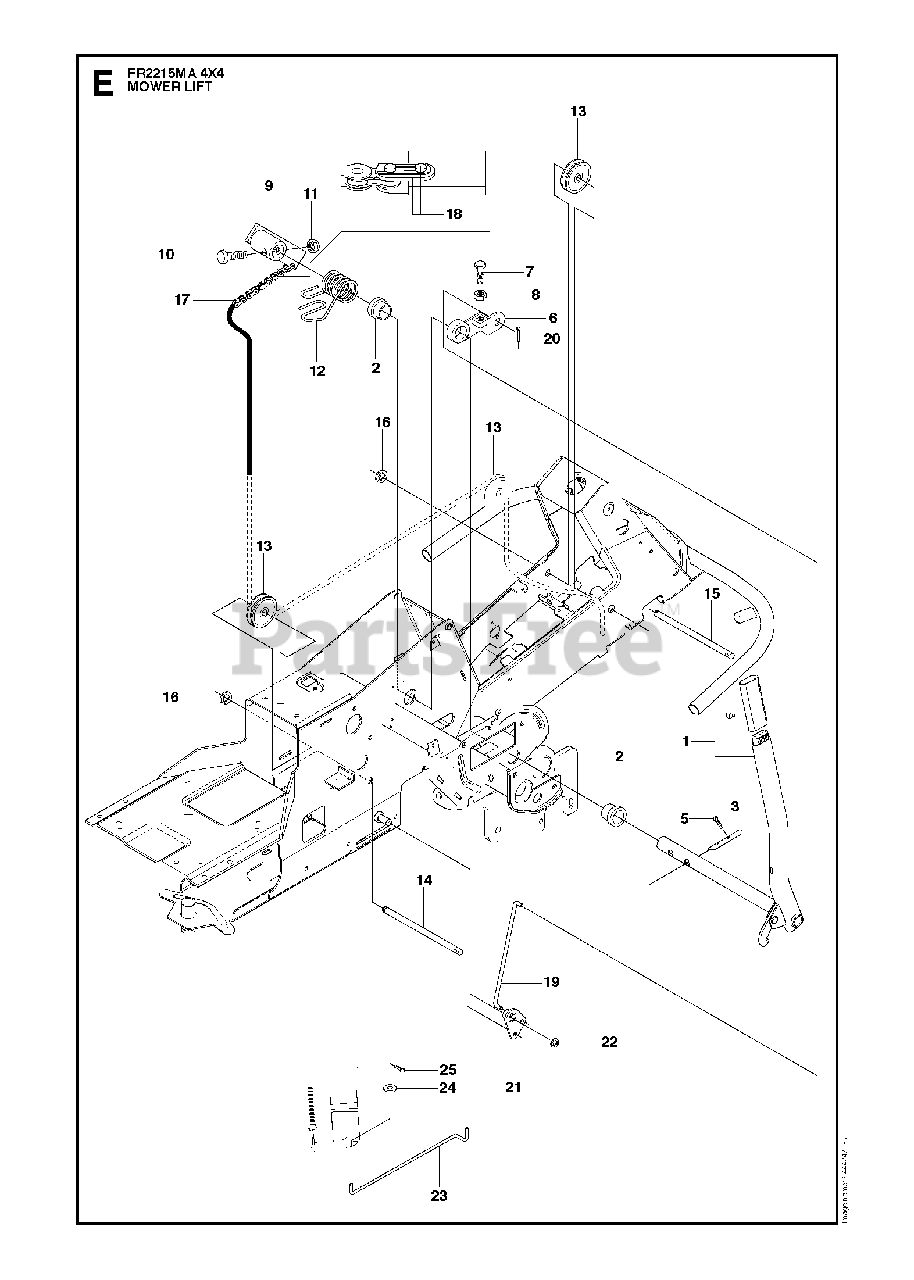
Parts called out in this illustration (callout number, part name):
1	LIFTING LEVER ASSY
2	BUSH
5	SPLIT PIN
6	LEVER CLUTCH
9	LIFTING ARM
16	LOCK RING
19	CONNECTION ROD
20	SPLIT PIN
22	RETAINING RING
23	CONNECTION ROD
25	SPLIT PIN
